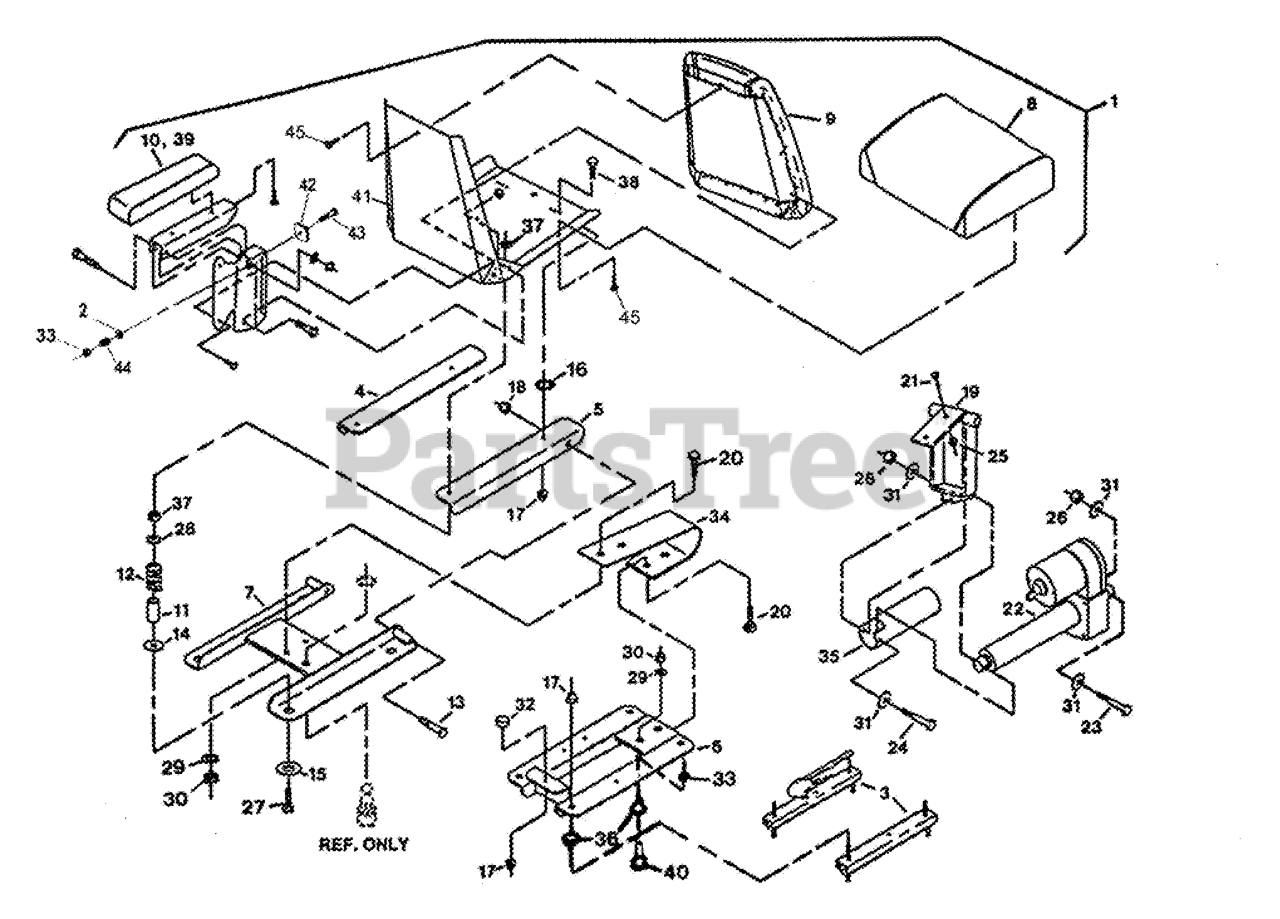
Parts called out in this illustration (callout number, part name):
1	KIT,SEAT W/ARMREST ADJ.
2	WASHER-PLAIN
4	RAIL,SEAT LH
5	RAIL,SEAT RH
8	CUSHION,SEAT BOTTOM
9	CUSHION,SEAT BACK
10	CUSHION,ARMREST RH
11	BUSHING,SPRING GUIDE
12	SPRING-INDICATOR, REVERSE
13	SCREW-HH
14	SCREW-HH
16	WASHER-FLAT
18	NUT-LOCK, NI
20	SCREW-HH
21	SCREW-HH
23	SCREW-HH
24	SCREW-HH
25	NUT-HHF, WHIZ
26	NUT-LOCK
27	BOLT,TAP HH
28	WASHER-FLAT
29	WASHER-LOCK
30	NUT-HH
31	WASHER-FLAT
32	BUMPER-RUBBER
33	NUT-LOCK, NI
35	GUARD,ACTUATOR
36	SPACER-TRACK
37	NUT-HEX
39	CUSHION,ARMREST LH
40	SCREW-PPH
41	FRAME-SEAT
42	TAB,ARMREST ADJUSTMENT
43	SCREW-HH
44	SPRING-TANK, FUEL
45	BOLT-SEAT
